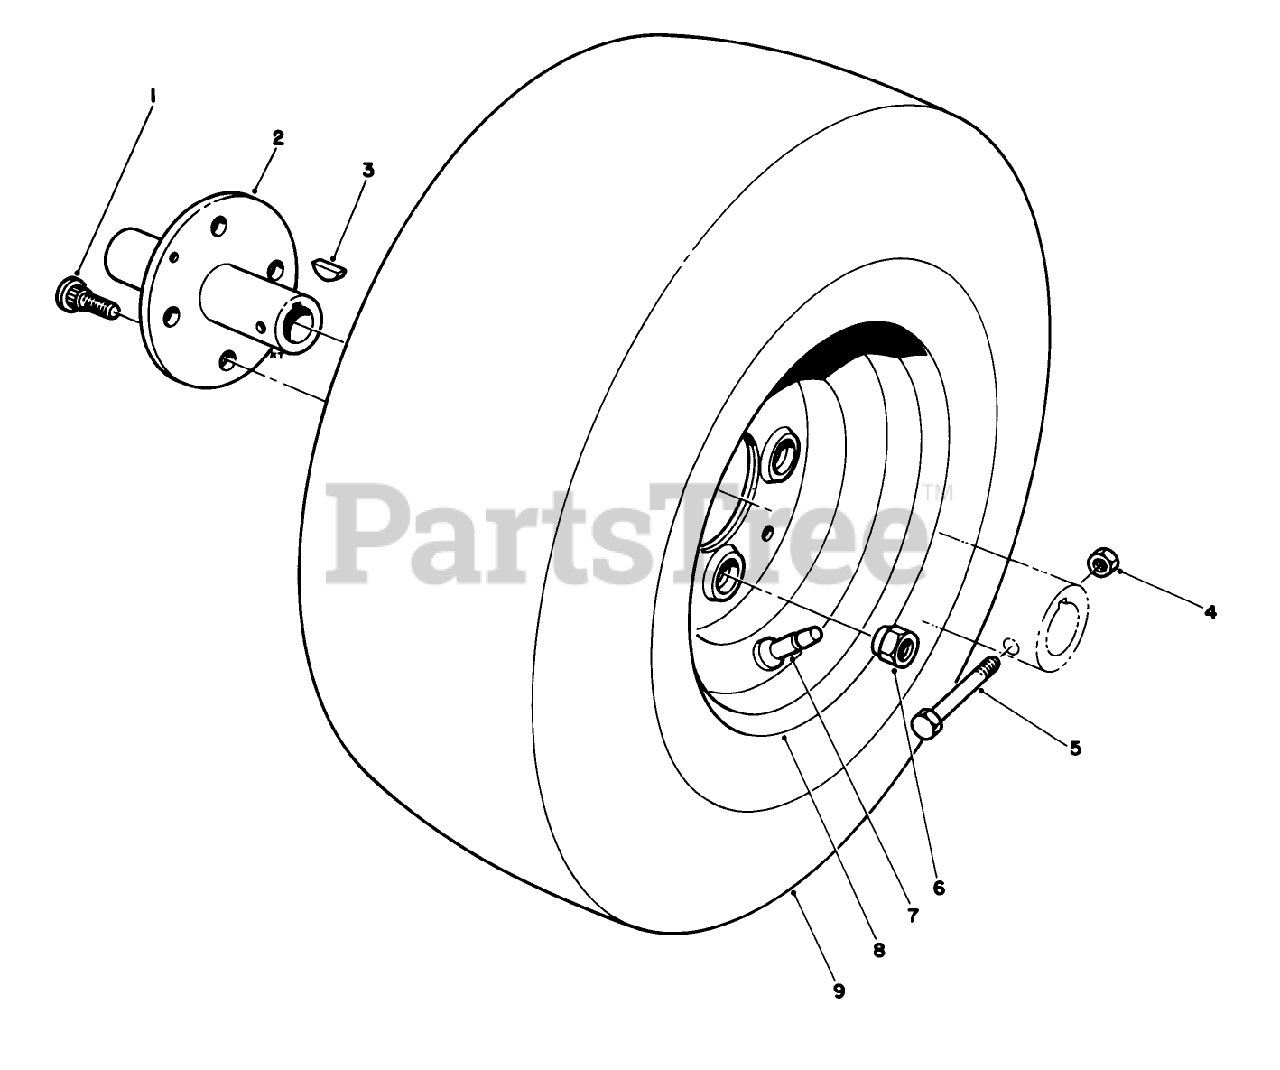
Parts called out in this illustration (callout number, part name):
1	1/2-20X1.25 BOLT
2	WHEEL HUB
3	KEY-WOODRUFF
4	NUT-LOCK, NI
5	SCREW-HH
6	NUT-LUG
9	TIRE-4-PLY
